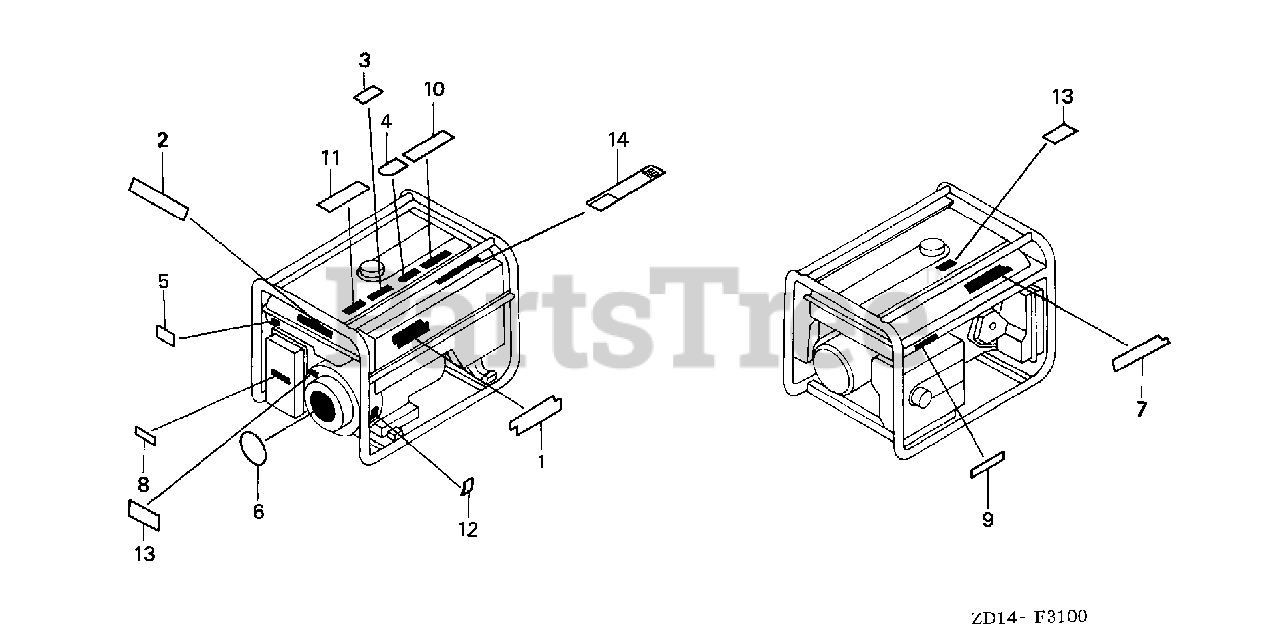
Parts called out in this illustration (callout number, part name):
1	MARK, EMBLEM
1	EMBLEM
2	PLATE, CAUTION
3	LABEL, RAIN WARNING (ENGLISH)
4	MARK, CAUTION (ENGLISH/FRENCH/SPANISH)
5	MARK, CHOKE
8	MARK, AIR CLEANER
9	MARK, EX. CAUTION (ENGLISH/FRENCH)
10	MARK, CAUTION (ENGLISH/FRENCH/SPANISH)
11	LABEL, CONNECT WARNING (ENGLISH)
12	MARK, OIL CAUTION
14	MARK, WARNING (GFCI)
